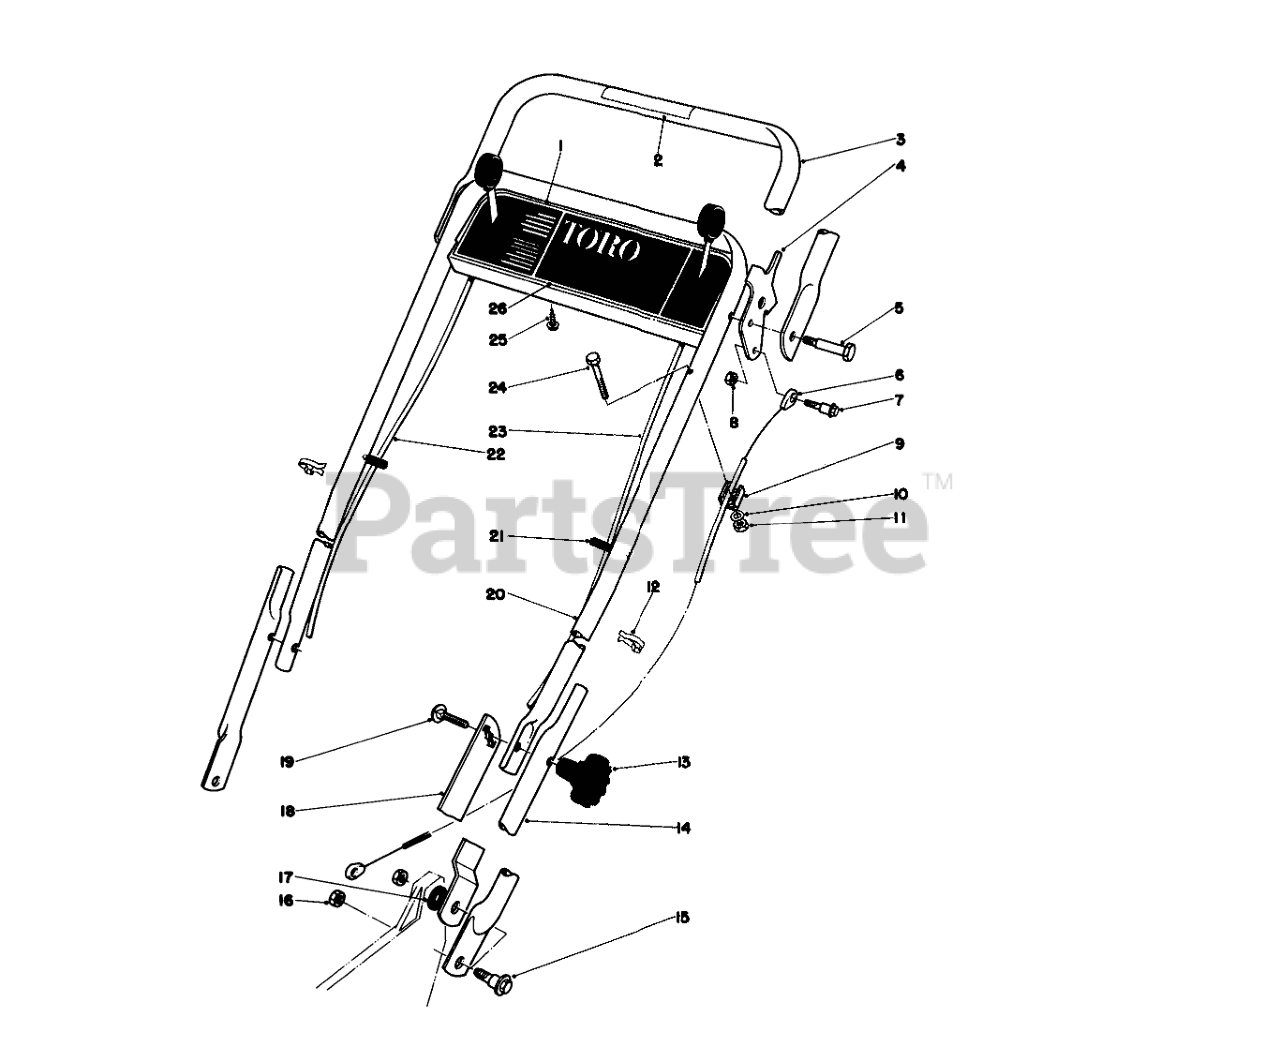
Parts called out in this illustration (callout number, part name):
1	Control Panel
2	Decal-Traction Control
3	Demand Handle
4	Demand Handle Stop
5	BOLT-SHOULDER
6	DEMAND HANDLE CABLE
7	Shoulder Bolt
8	NUT-HEX, SIDE DEFORM
9	CLAMP-CABLE
10	WASHER-FLAT
11	NUT-LOCK, NI
12	BOWDEN CLIP
14	LOWER HANDLE
15	Screw
16	Nut
17	SPACER
18	Handle Latch L.H.
19	SCREW-CARR
20	Upper Handle
21	CAP-VINYL
22	GROUND SPEED CONTROL
23	Throttle Control
24	SCREW-HH
25	SCREW-HWHTF
26	Decal Control Panel
